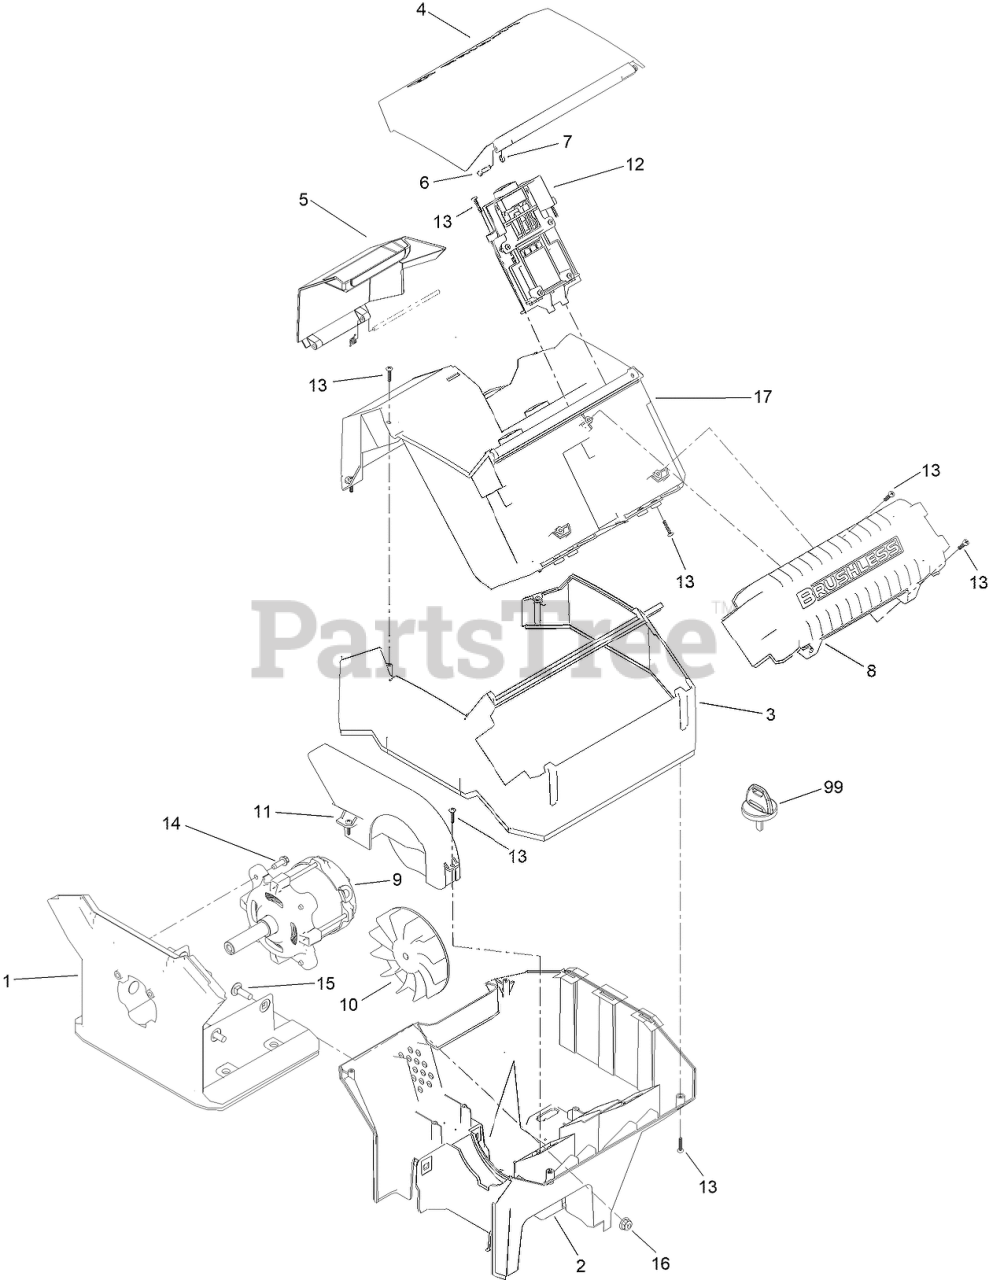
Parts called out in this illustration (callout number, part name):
1	MOTOR MOUNT
2	HOUSING-MOTOR
3	COVER-CONTROLLER
4	DOOR-TOP
5	DOOR-BOTTOM
6	PIN-BATTERY COVER
7	RING-RETAINING
8	MOTOR CONTROLLER ASM-POWERHEAD
9	MOTOR-60V, 2 STAGE
10	FAN-FC
11	COVER-FAN
12	BATTERY TRACK ASSEMBLY
13	SCREW-PPH
14	SCREW-HWHTF
15	BOLT-CARR
16	NUT-HF, NI
17	BUCKET-BATTERY
99	KEY-60V 2 STAGE POWER HEAD
